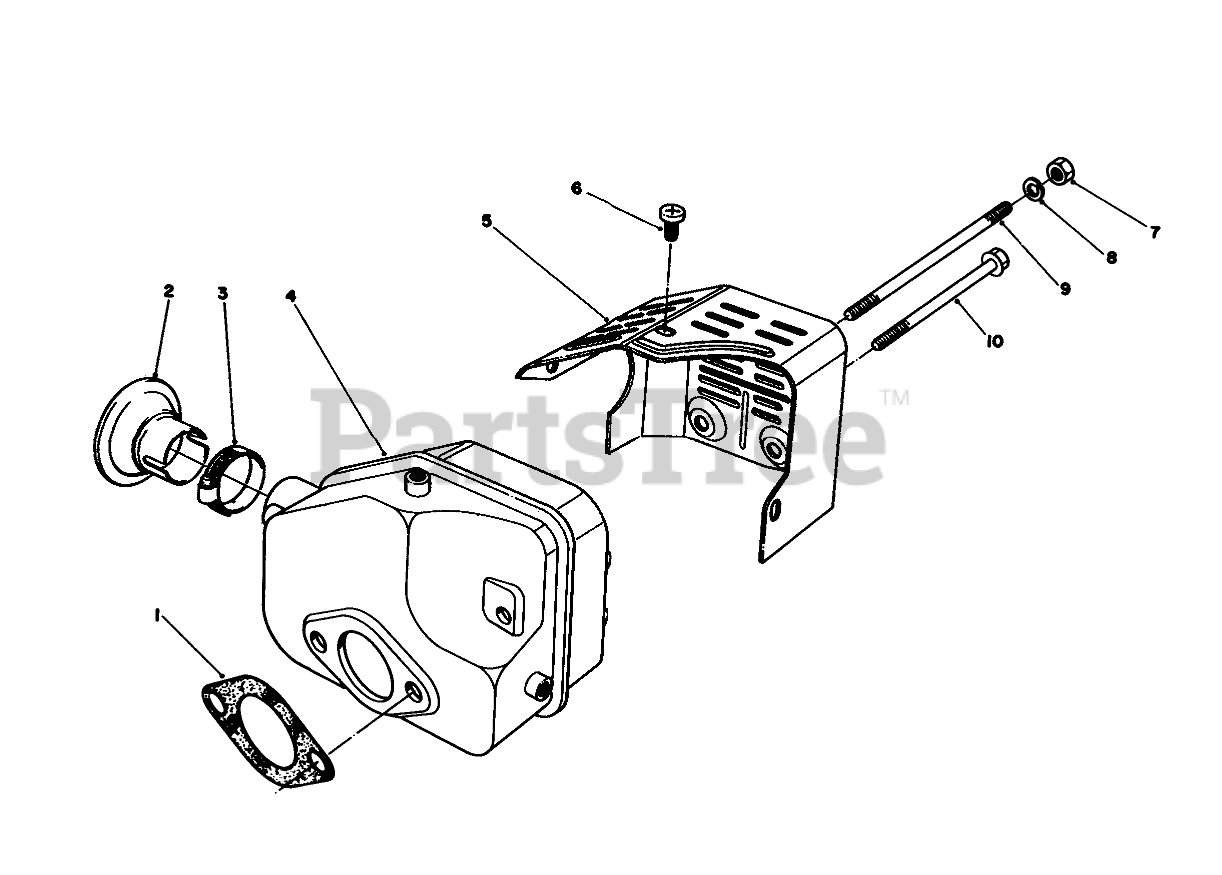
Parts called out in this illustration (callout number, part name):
1	GASKET
2	Arrestor-Spark
3	Clamp-Hose
4	Muffler
5	COVER
6	SCREW
8	WASHER-LOCK
